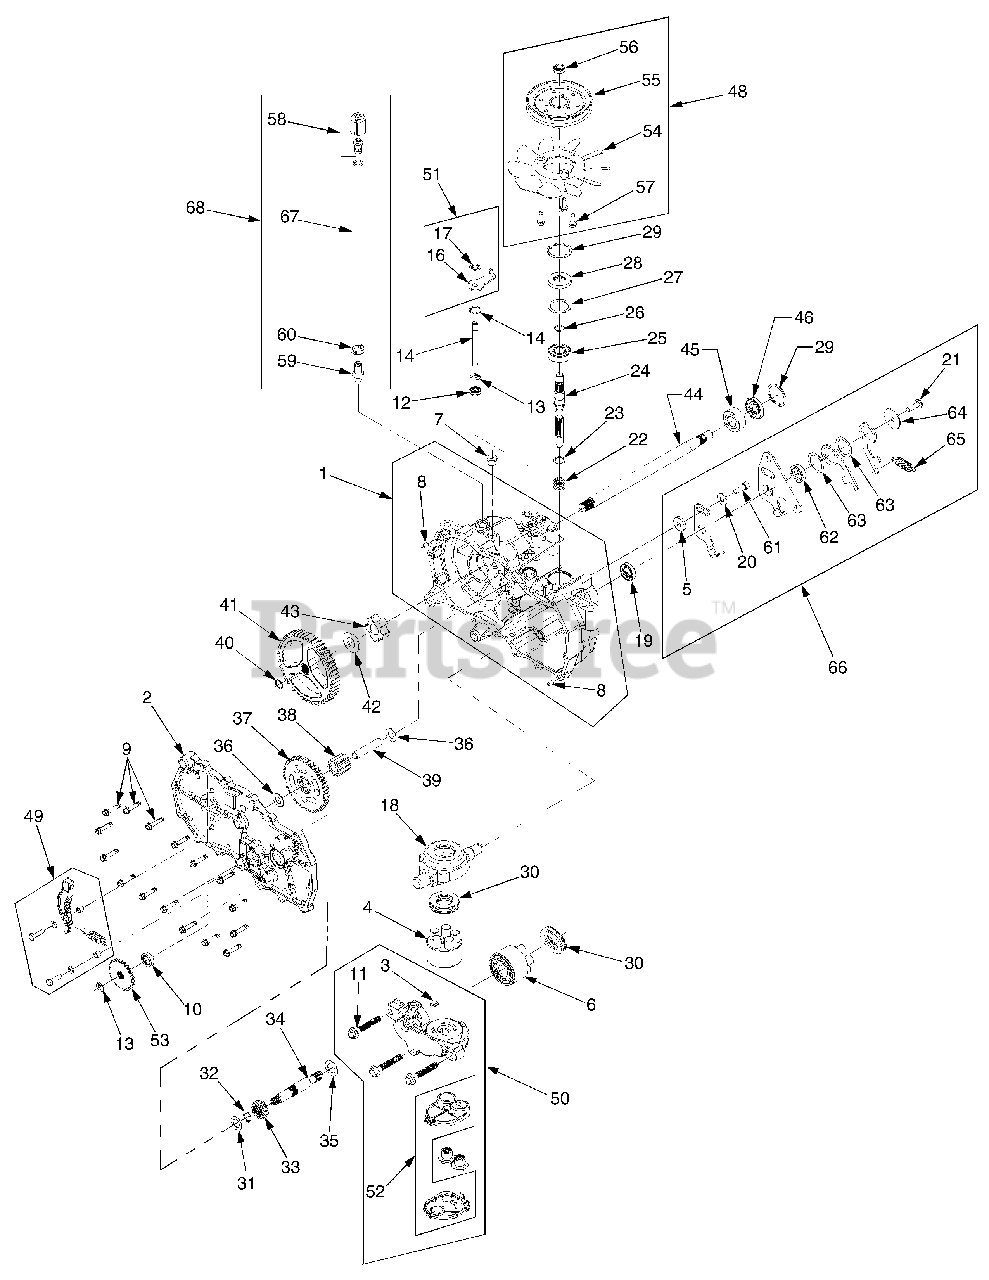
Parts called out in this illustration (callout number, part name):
1	Housing Assembly, Main LH
2	Side Assembly, LH
3	Plate, Bypass
4	Pump Block Assembly
5	Spacer, .32 x 1.005
6	Motor Block Assembly
8	Pin, Stainless
9	Screw, Hex Self Tapping, 1/4-20 x 1.25
10	Seal, Lip, .5 x .88 x .25
11	Bolt, Hex Flange, 3/8-24 x 2.5
12	Seal, Lip, .375 x .75 x .25
13	Ring, Retaining, .375 Ext.
14	Rod, Bypass
15	Ring, Retaining, .75 Int.
16	Arm, Bypass
17	Ring, Retaining, .375 Push
18	Swashplate, Trunnion
19	Seal, Lip, 18 x 32 x 7
20	Washer, Flat, 11/32 x 7/8 x 1/16
21	Screw, 5/16-24 x 1.0
22	Spring, Compression
23	Washer, .591 x .787 x .04
24	Shaft, Input
25	Bearing, Ball, 17mm x 40 x 12
26	Ring, Wire Retaining, .561
28	Seal, Lip, 17 x 40 x 7
29	Ring, Retaining
30	Bearing, Thrust, 30 x 52 x 13
31	Washer, Flat, 5/8 x 1.0 x .05
32	Ring, Retaining
33	Gear, Pinion, 13T
34	Shaft, Motor
35	Washer, .71 x 1.16 x .04
36	Washer, HT, .5 x 1.0 x .032
37	Gear, 10T/48T
38	Gear, Jackshaft, 10T
39	Pin, Jackshaft
40	Ring, Spiral Retaining
41	Gear, Bull, 52T
42	Washer, 3/4 x 1.5 x .13
43	Bearing, Sleeve
44	Axle, spline
45	Bushing, .752 x 1.571 x .625
46	Seal, Lip, .75 x 1.577 x .25
47	Kit, Expansion Plate, LH
48	Kit, Fan-Pulley
49	Kit, Brake Arm
50	Kit, Center Section-Filter LH
51	Kit, Bypass Arm
52	Kit, Filter
53	Disc, Brake Cog
54	Fan, 7" 10 Blade
55	Pulley, 4.5
56	Nut, Hex Insert Lock, 1/2-20
57	Screw, Hex Wash. Hd. Tapp 1/4-20
58	Cap, Vent Assembly
59	Fitting, Sraight, 9/6-18
60	Clamp, Pinch
61	Screw, Hx Patch, 5/16-24 x 1.0
62	Bushing, Pilot, 1.125
63	Washer, Plastic
64	Washer, 1.5 x .34 x .062
65	Spring, Extension
66	Kit, Return Assembly
67	Hose, .5 x 15.0
68	Kit, Breather Assembly
